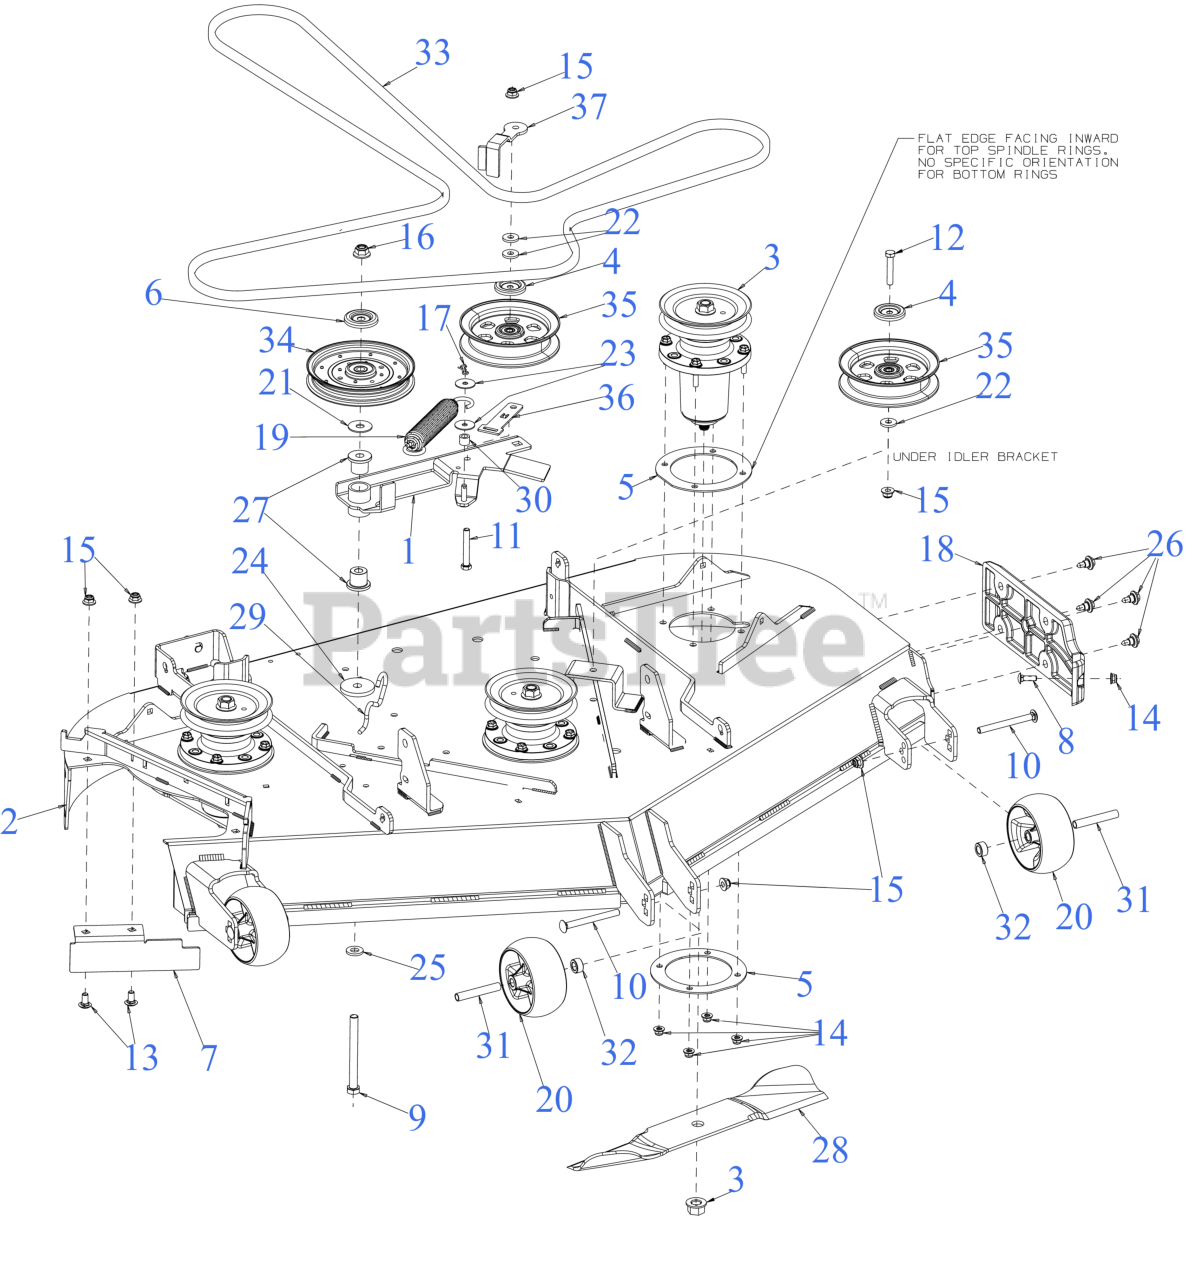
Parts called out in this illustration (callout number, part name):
1	54/60" DECK IDLER ASSEMBLY
2	54" FAB DECK SHELL
3	SPINDLE ASSEMBLY
3	Cub Cadet 54" SPINDLE ASSEMBLY (07416)
4	PULLEY CAP 1.875 DIA
5	SPINDLE PLATE
6	PULLEY CAP (.540 x 2.041 DIA)
7	BAFFLE
8	CARRIAGE BOLT 5/16-18 x 1.00
9	BOLT-HEX 1/2-13X5.0 GR5
10	CARRIAGE BOLT 3/8-16 x 4.00 GR5
11	HEX SCREW-3/8-16X2.5 GR5
12	SCREW 3/8-16 x 2.0 GR5
12	SCREW 3/8-16 x 2.0 GR 8
13	CARRIAGE BOLT 3/8-16 x .75
14	FLANGE LOCK NUT 5/16-18
17	BOW TIE COTTER PIN 1/4-5/16
18	DECK SKID PLATE
19	SPRING 1.25" DIA x 8.5" LONG
20	DECK WHEEL
20	WHEELS-DELUXE 5"
21	WASHER .51 x 1.5 x .07
22	FLAT WASHER .385 x 1.00 x .135
23	FLAT WASHER .322 ID x 1.25 x .060
24	FLAT WASHER .53"x2.125"x.25"
25	FLAT WASHER .531X1.060X.134
26	SHOULDER SCREW .43X.29X5/16-18 TT
27	FLANGE BEARING
29	DECK SPRING HOOK
31	SPACER .38X.49X3.05LG
32	SPACER-.505 1D
33	V-BELT B SEC x 148.25
33	Cub Cadet 54" DECK DRIVE BELT
34	IDLER PULLEY 6.0" DIA
35	5" FLAT IDLER PULLEY
36	BELT KEEPER
37	54/60" IDLER KEEPER
